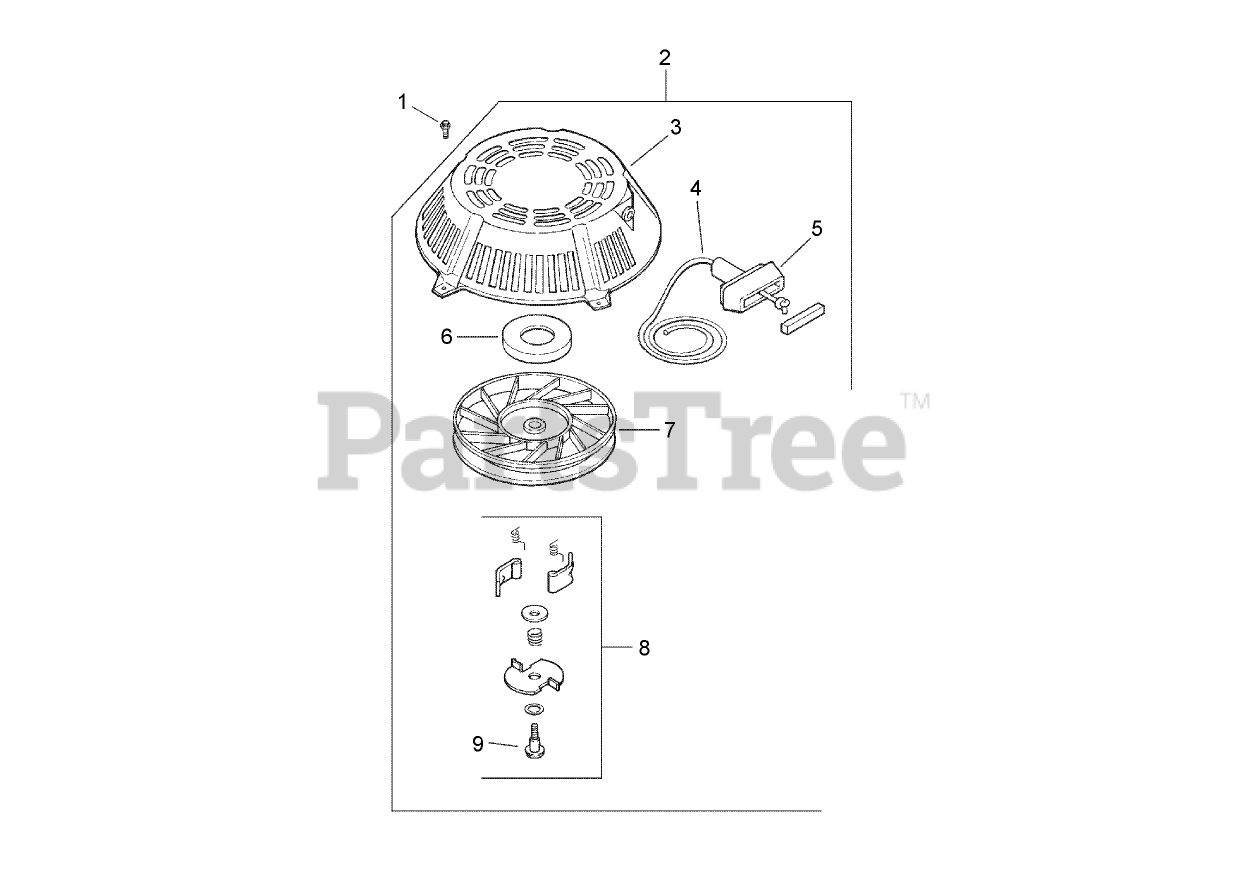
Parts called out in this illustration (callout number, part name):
1	Screw-HF (M5x0.8x10)
2	Retractable Starter ASM (Includes 3-9)
3	Housing-Starter
4	Rope-Starter
5	Handle-Start, Recoil
6	Spring and Keeper
7	Pulley
8	Dog Repair Kit (Includes 9)
9	Screw-pozi driv
